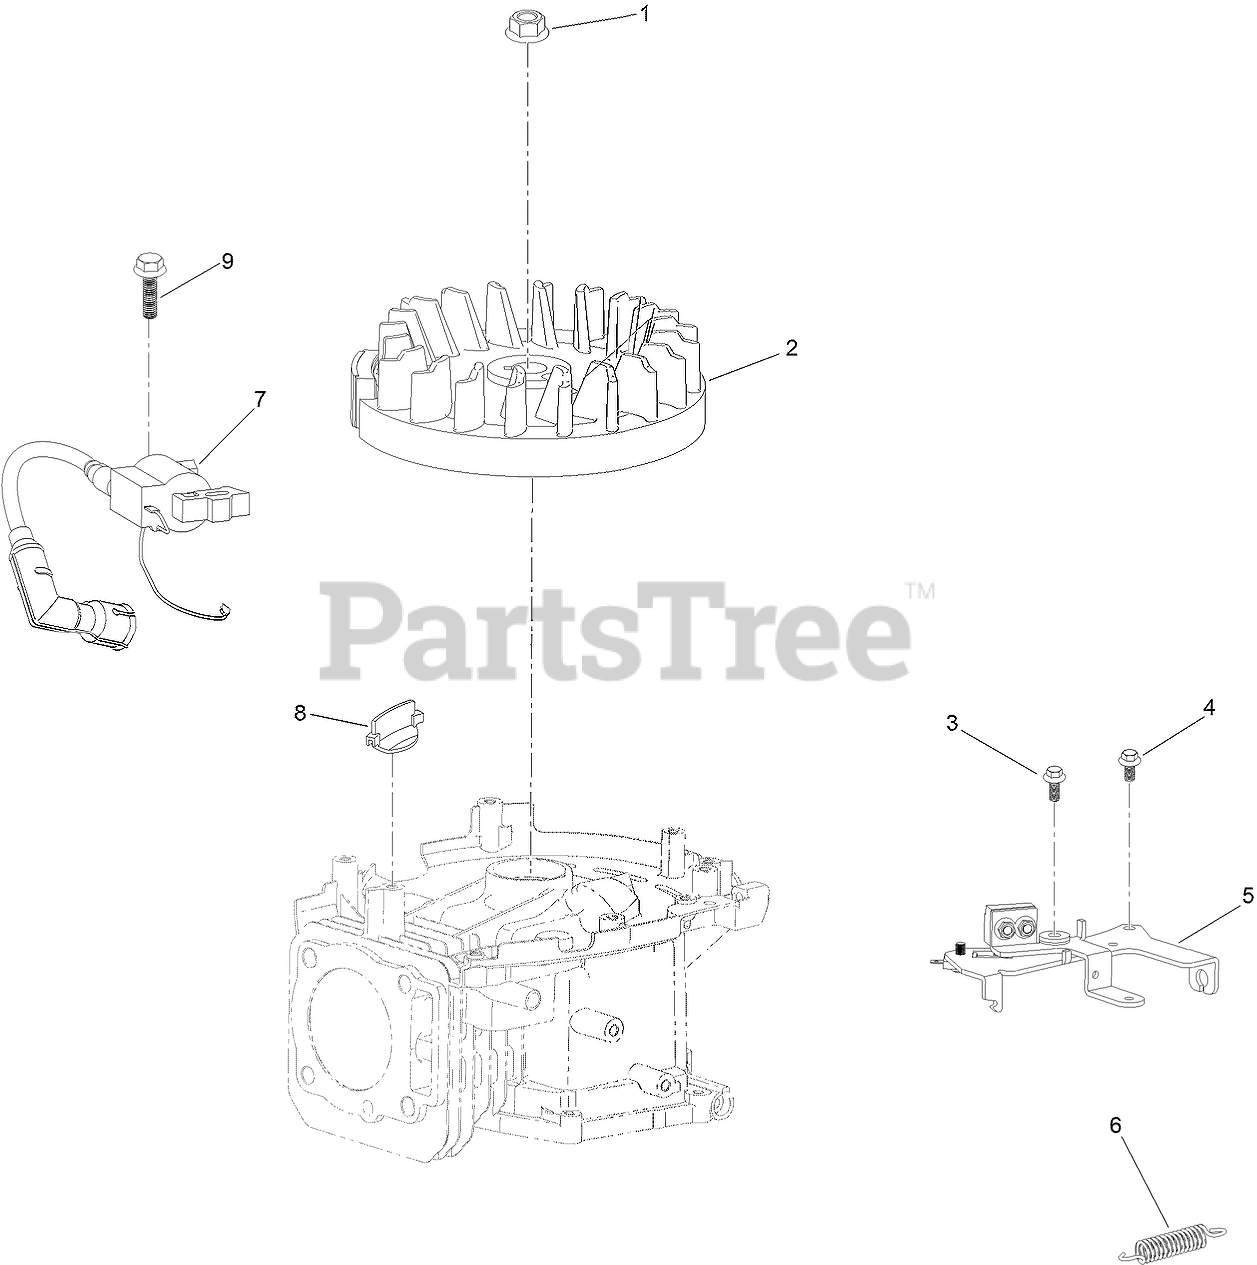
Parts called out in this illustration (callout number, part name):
1	NUT-FLANGE
2	FLYWHEEL
3	BOLT-FLANGE
4	SCREW-HHF
5	BRAKE ASM
6	SPRING-BRAKE
8	GUARD-FLYWHEEL
9	SCREW-HHF
